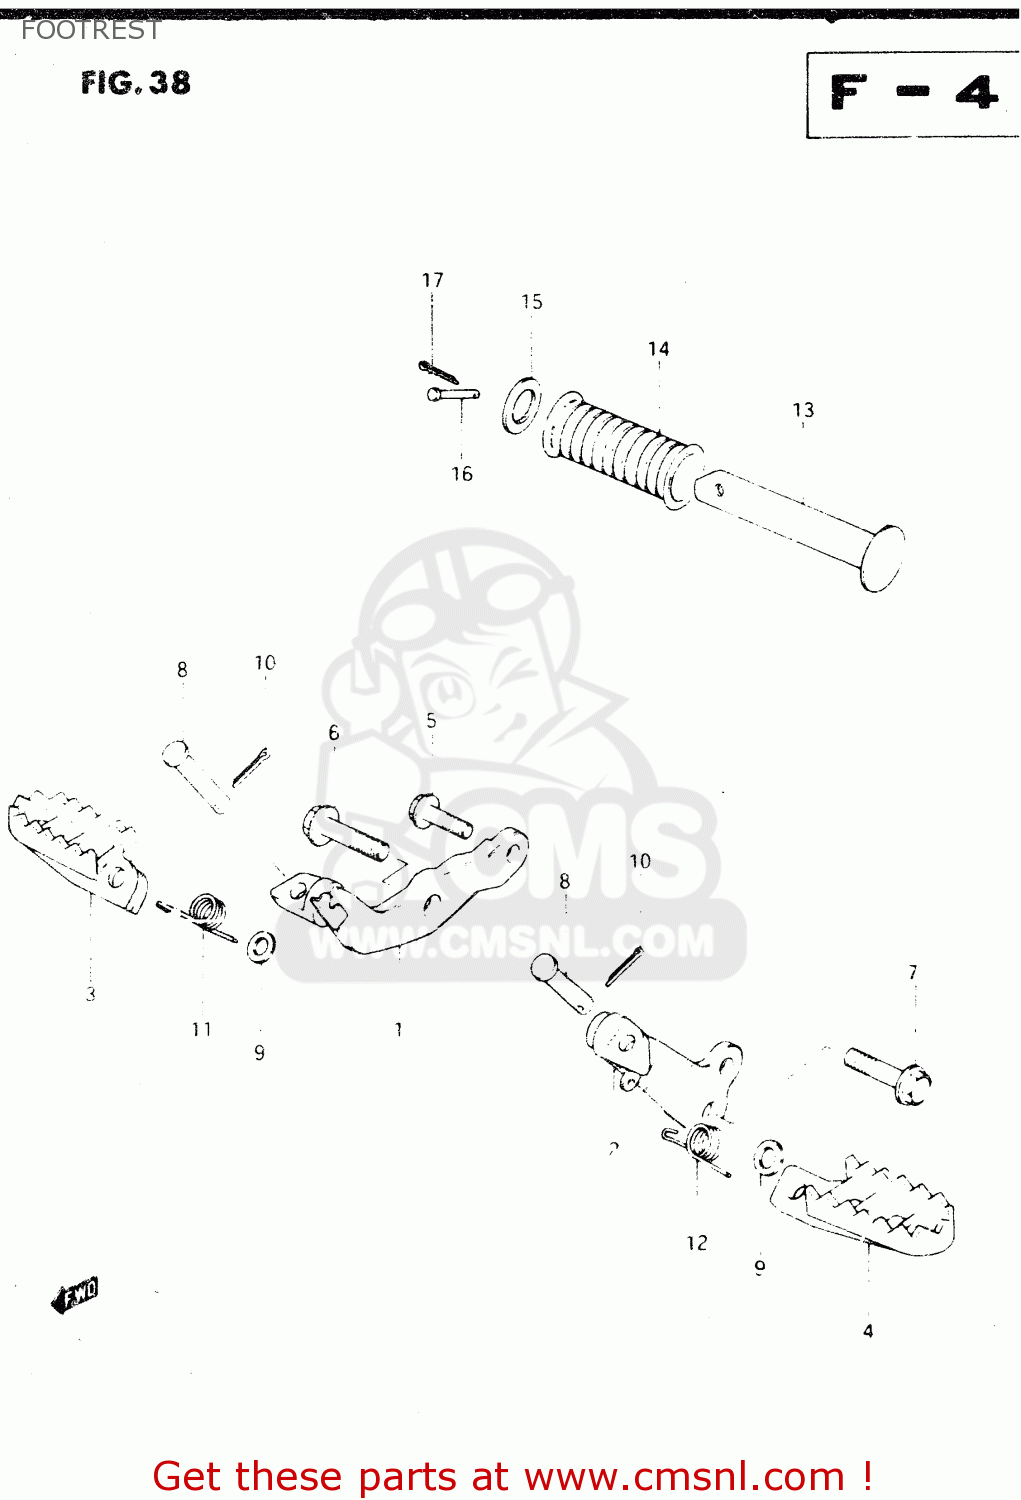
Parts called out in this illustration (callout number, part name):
1	BAR,FRONT FOOTREST
2	BAR,FRONT FOOTREST,LEFT
3	FOOTREST,RIGHT
4	FOOTREST
5	BOLT
6	BOLT, RH
7	BOLT
8	PIN
9	WASHER
10	PIN 20X20
11	SPRING
12	SPRING
13	BAR,FOOTREST RUBBER
14	RUBBER,PILLION FOOTREST
15	WASHER (19.5X32X2)
16	PIN
17	PIN 20X20
